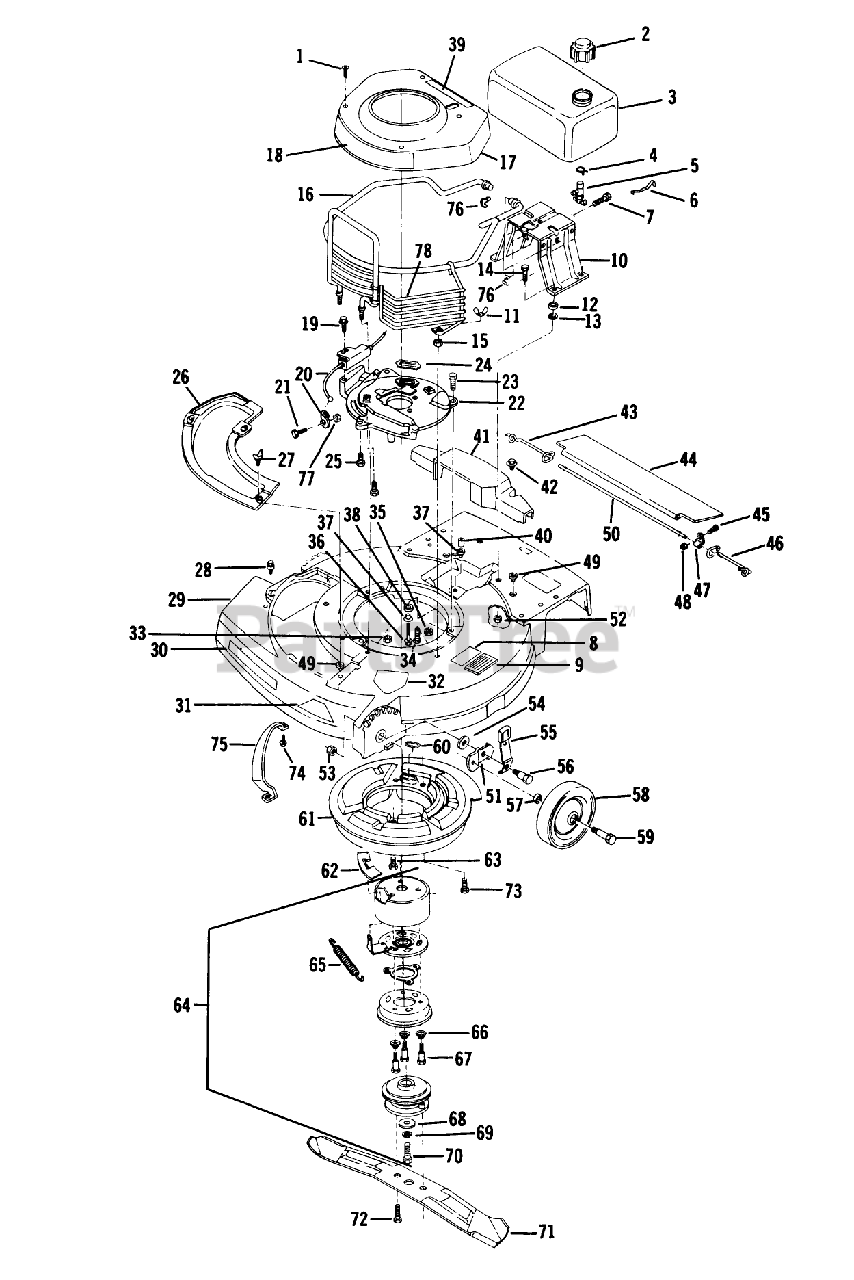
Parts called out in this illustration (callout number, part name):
1	SCREW - SELF TAPPING
2	FUEL CAP & INSERT
4	CLAMP - HOSE S
5	VALVE&SCREEN SM
7	SCREW S
9	PAD FOOT
14	BOLT PIONEER
15	LOCKNUT E
17	SHROUD S
25	SCREW V
27	WING SCREW LAWRE
29	Housing-21" Push
33	NUT-LOCK F
35	NUT-LOCK F
37	SPACER ECK PRES
38	GROMMET
42	SCREW SEMS TRM HEX HD
43	SPRING;TRAILING SHIELD RH
46	SPRIG T/SHLD ASOC
47	CLAMP ROD KMC
48	LOCKNUT E
50	ROD 21" ADVANCE
52	LOCKNUT E
53	LOCKNUT
57	WASHER WROUGHT
58	WHEEL & TIRE ASSY
59	BOLT-SHOULDER
67	SCREW,SHOULDER SM
72	SCREW SEMS
75	BAR-TOE
77	LOCKNUT E
